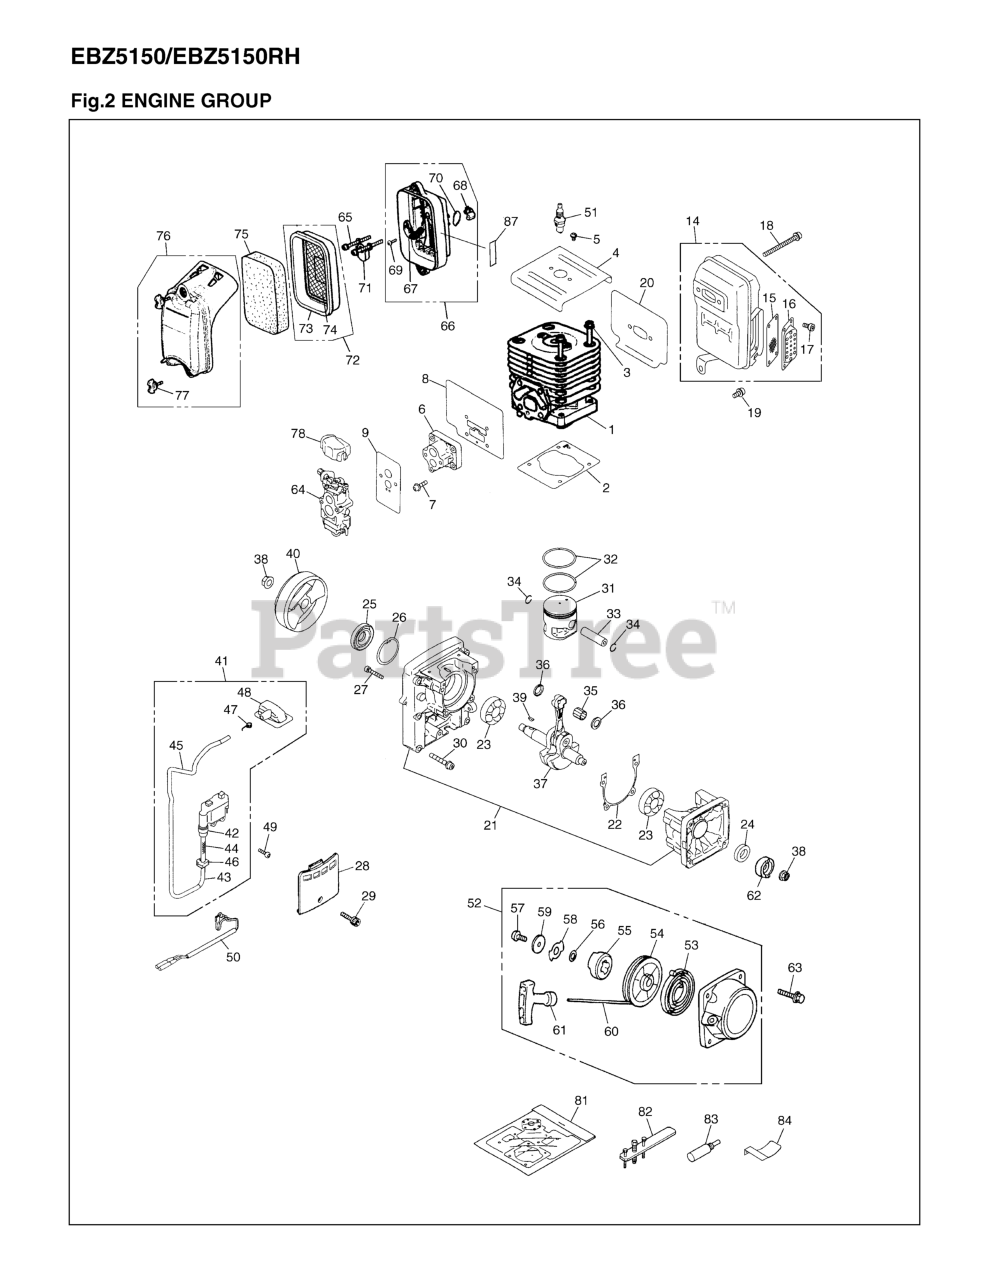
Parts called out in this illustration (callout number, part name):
1	CYLINDER
2	GASKET, BASE
3	BOLT
4	PLATE, CYLINDER
5	SCREW TORX
6	INSULATOR
7	BOLT
8	GASKET, INSU
9	GASKET, CARB
15	ARRESTER
16	DIFFUSER
17	Bolt
18	BOLT
19	BOLT
20	GASKET, MUFFLER
21	CRANKCASE-C
22	GASKET, CASE
23	BEARING (REPLACES 2810-21240)
24	SEAL, OIL 15 X 25 X 7
25	SEAL (REPLACES 1400-21220)
26	RING, SNAP, M35 X 1.5
27	BOLT
28	COVER
29	BOLT TORX
30	BOLT TORX
31	PISTON
32	RING
33	PIN
34	RING, SNAP
35	BEARING
36	WASHER (RPLS 1491-41510)
37	CRANKSHAFT COMP
38	NUT, M10
39	KEY
41	COIL ASSY
44	TUBE
45	TUBE
46	GROMMET
48	CAP
49	BOLT TORX
50	CORD-C
51	SPARK PLUG
52	RECOIL ASSY
53	SPRING (RPLS -75220)
54	REEL
55	DOG
56	WASHER
57	SCREW
58	RETAINER (RPLS 1861-75161)
59	WASHER
60	ROPE
61	KNOB
62	PULLEY (RPLS -75210)
63	BOLT, TORX
64	CARBURETOR
65	BOLT
66	BODY-A
67	PLATE,CHOKE
68	LEVER
69	SCREW
70	RING,O
71	PLATE
72	PACKING-C
73	PACKING
75	ELEMENT
76	COVER ASSY
77	KNOB
78	COVER
81	GASKET KIT
82	PULLER ASSY
83	STOPPER (TOOL)
84	GAUGE
87	LABEL, CHOKE
